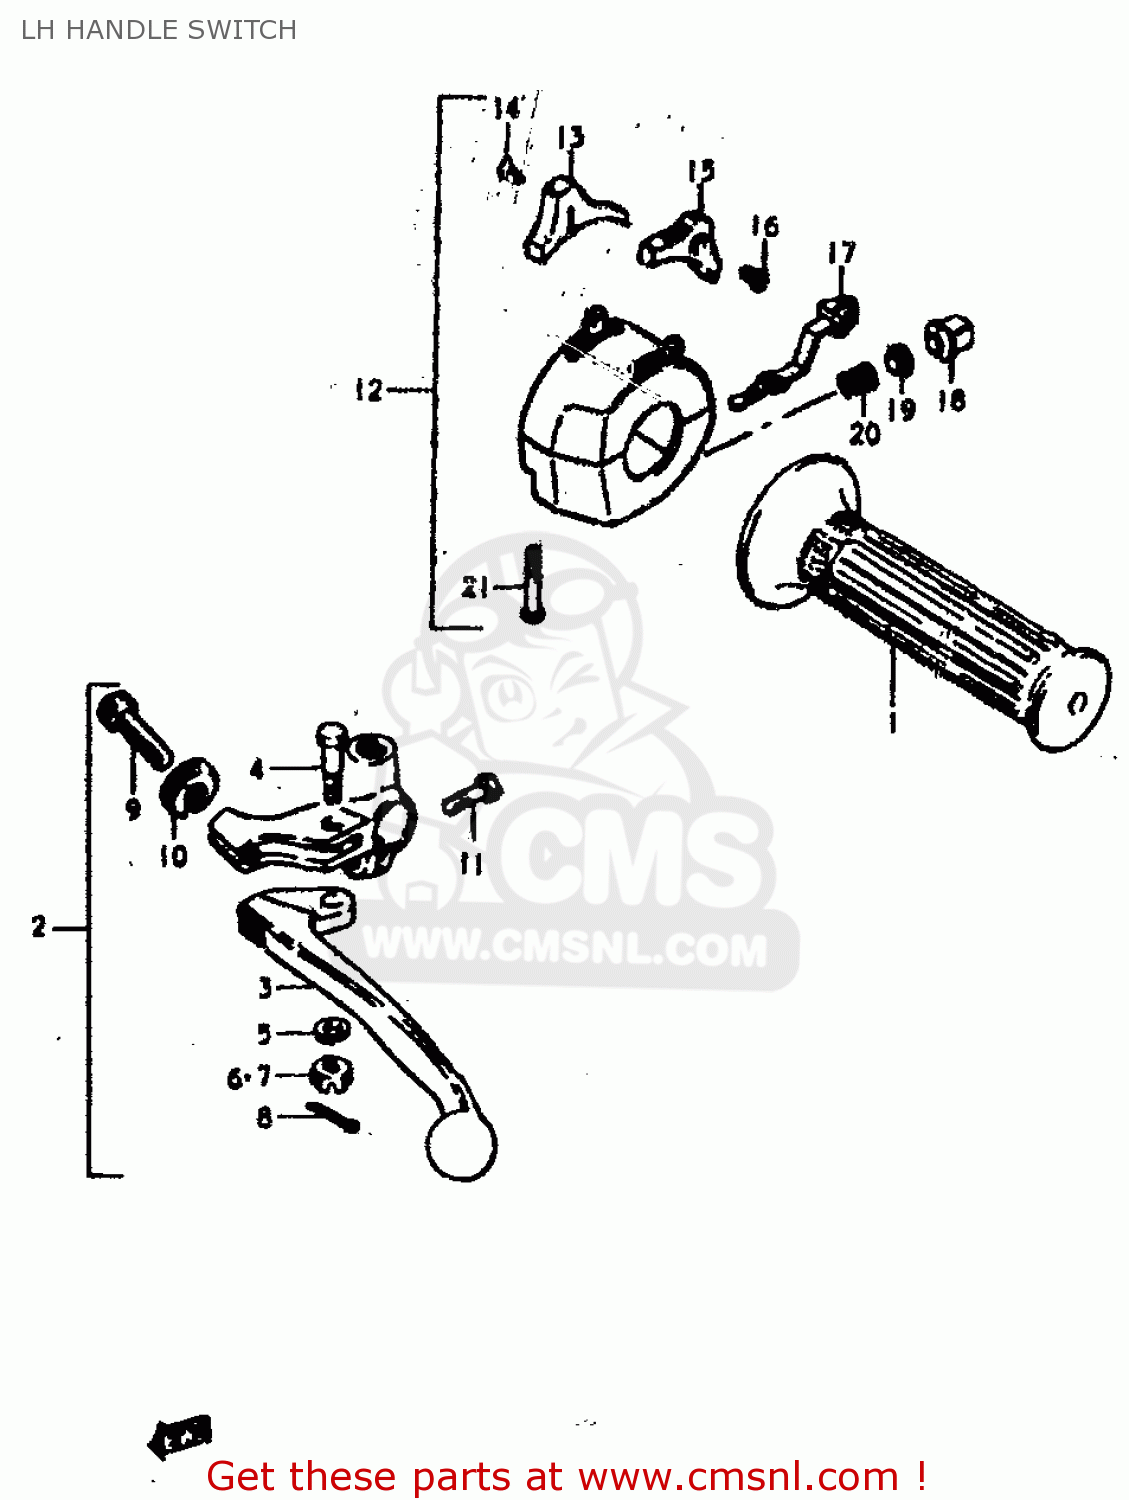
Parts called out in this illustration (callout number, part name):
1	GRIP,L
2	LEVER ASSEMBLY
3	LEVER,CLUTCH
4	BOLT,LEVER
5	LOCK WASHER
6	NUT,LEVER FITTNG
8	COTTER PIN
9	ADJUSTER,CABLE
10	NUT,CABLE ADJUSTER
11	BOLT
12	SWITCH ASSY,HANDLE LH
13	KNOB,LIGHTING SWITCH
14	SCREW
15	KNOB,DIMMER SWITCH
16	SCREW
17	KNOB,TURNSIGNAL
18	BUTTON,HORN
19	CONTACT
20	SPRING
21	SCREW
